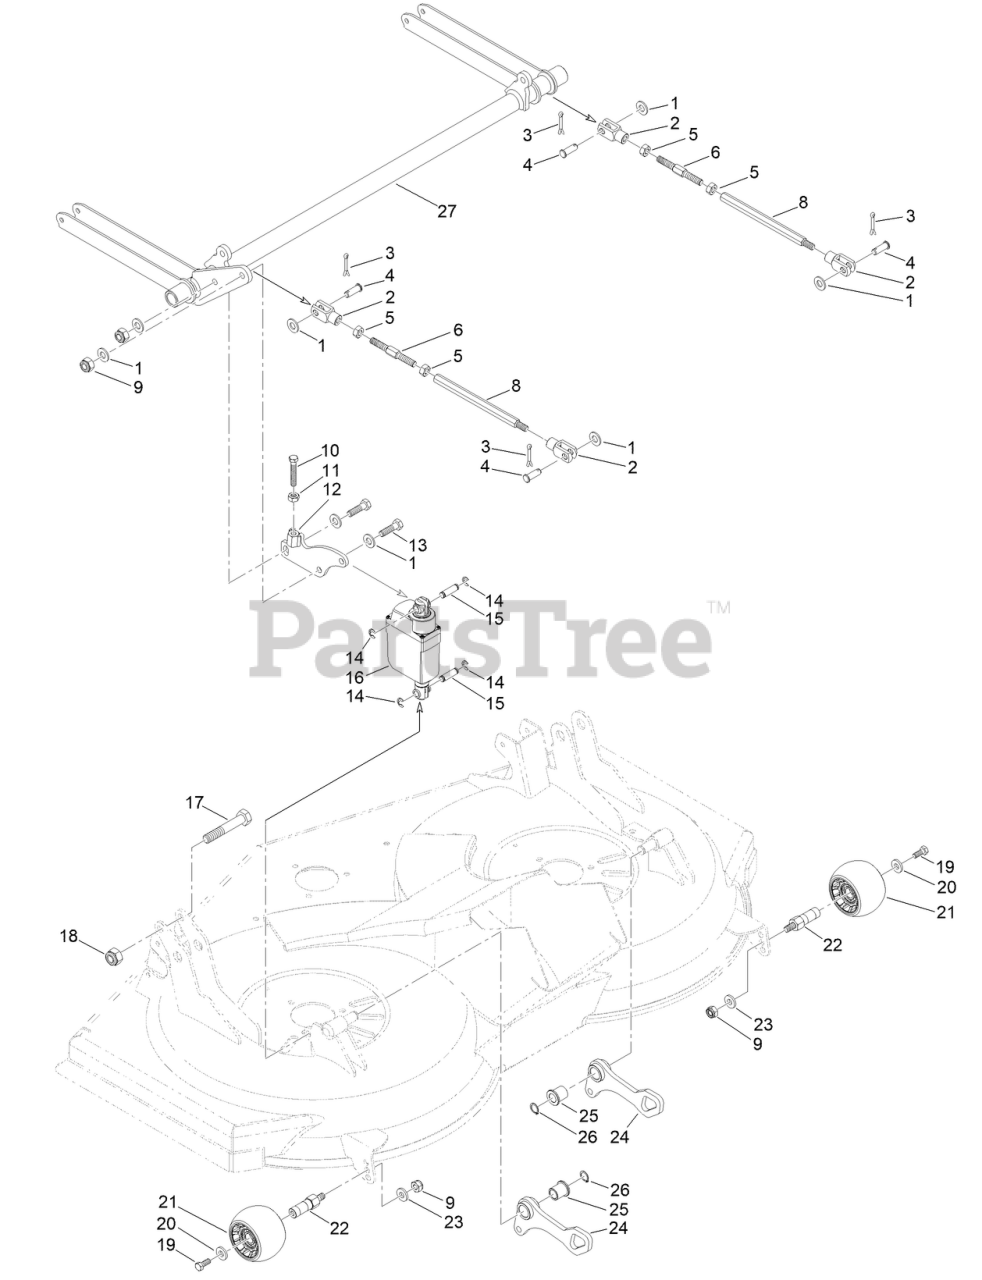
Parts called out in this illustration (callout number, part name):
1	WASHER
3	PIN-SPLIT
6	ROD-ADJUSTMENT
10	SCREW-HH
12	BRACKET, ELECTRIC ACTUATOR
14	RING SNAP
15	PIN, ELECTRIC ACTUATOR
16	ACTUATOR, ELECTRIC
17	SCREW, HH CAP
20	WASHER
21	WHEEL-ANTI SCALP
22	PIVOT, ANTI-SCALP WHEEL
23	WASHER
24	PIVOT-ARM, CONNECTING ROD
25	BUSHING
26	RETAINER
27	TORSION-BAR, DECK
